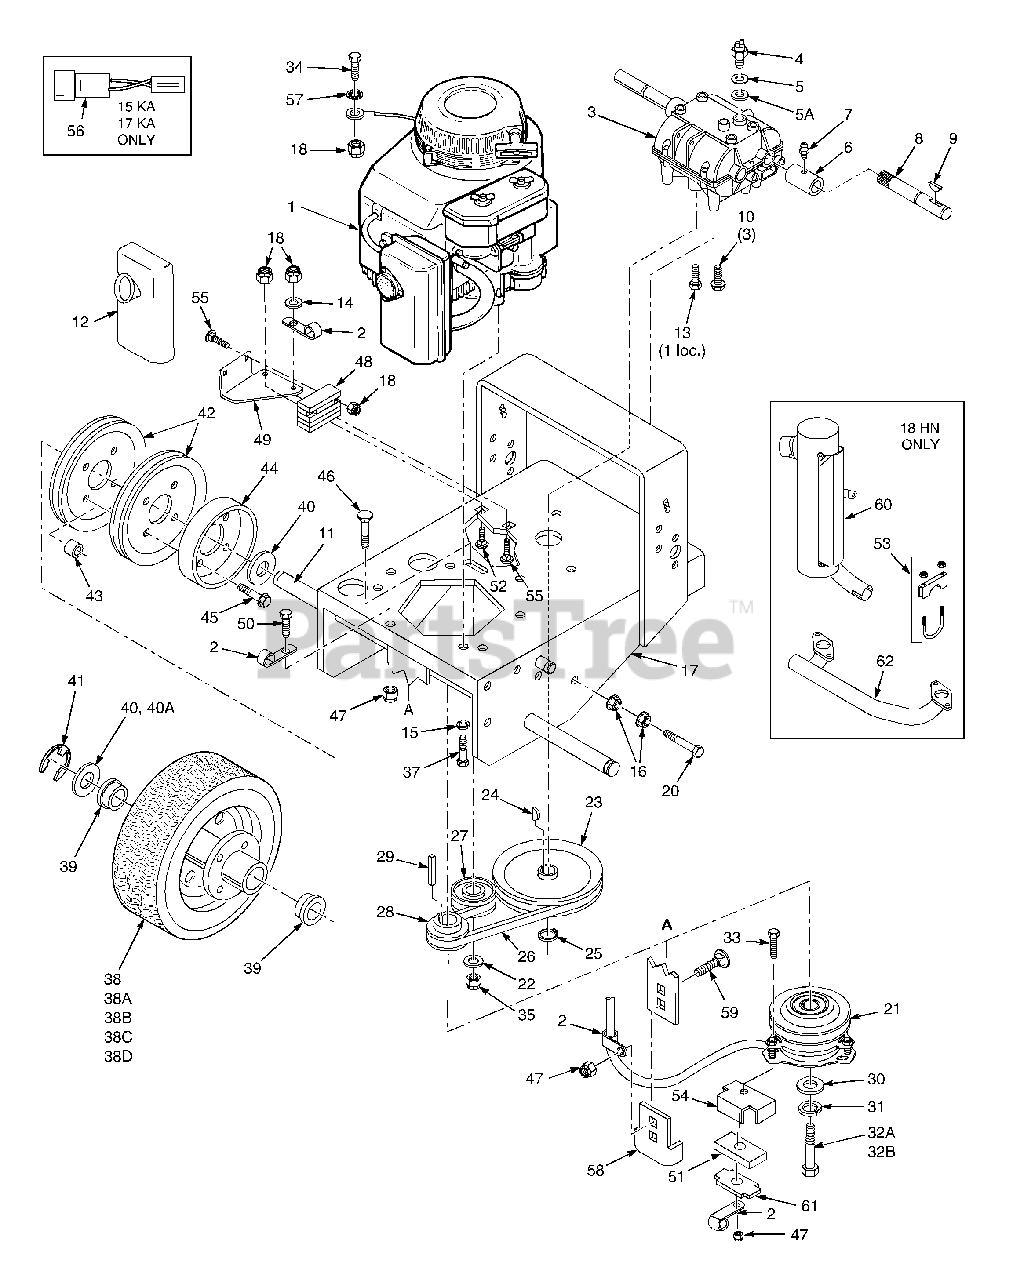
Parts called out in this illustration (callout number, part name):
1	Engine, 15HP Kawasaki (Spec FH451V-AS19)
1	Engine, 17HP Kawasaki (Spec FH500V-AS42)
2	Cable Clamp
3	Transmission, 5-speed (Peerless 700-070, 9 tooth spline)
4	Neutral Safety Switch
5	Fibre Washer, thin
5A	Fibre Washer, thick
6	Coupler, Jackshaft
7	Grease Fitting, straight 1/4-28
8	Jackshaft (fits SW32,36,48 & 52)
9	Key, Hi-Pro #9
10	Bolt, 5/16-18 X 3/4" Carriage
11	Wheel Axle (SW36,48 & 52)
12	Muffler (Purchase from Kawasaki)
13	Bolt, 5/16-18 X 3/4" Hex Head
14	Flat Washer 1/4" (.312 X .75 X .065)
15	Lock Wshr. 5/16"
16	Nut, 3/8-16 Serrated Flange
17	Engine Deck (fits SW32)
18	Nut, 1/4-20 Elastic Stop
19	Nut, 5/16-18 Serrated Flange
20	Bolt, 3/8-16 x 3-3/4" Hex Head
21	Electric Clutch (Ogura)
22	Washer, 3/8" (.391 x .938 x .105)
23	Pulley, Transmission Input
24	Key, Woodruff #9
25	Retaining Ring, 5/8" Ext, Basic
26	Belt, Transmission Drive
27	Idler Pulley, Transmission
28	Pulley, Traction Drive
29	Key, 1/4 x 1/4 x 3/4"
30	Flat Washer, 7/16" Special
31	Lock Washer, 7/16"
32A	Bolt, 7/16-20 x2-1/2" Hex Head
32B	Cpsrw, M10-1.5 x 55 Metric Hex Hd
33	Bolt, 5/16-18 x 1-3/4" Hex Head
35	Nut, 3/8-16 Elastic Stop
36	Flat Washer, 5/16"
37	Bolt, M8-1.25 x M25 Metric Hex Hd
38	Wheel Assembly (fits SW36,48,52)
38	Wheel Assembly
38A	Tire, 13 x 6.50-6, 2-ply (fits SW36,48,52)
38B	Rim & Bearing Assembly (fits SW36,48 & 52)
38C	Tire, 13 x 5.00-6 2-ply (SW32 only)
38D	Rim Assembly (SW32 only)
39	Wheel Bearing (OD 2.000 - 2.005)
40	Washer, 1-1/16 x 1-3/4 x 12 ga
40A	Washer, 1-1/16 x 1-1/2 x 18 ga
41	Retaining Ring, 1" Ext.- "E"
42	Pulley, Wheel Drive
43	Spacer, Wheel Pulley
44	Brake Drum
45	Bolt, 5/16-18 x 1-1/2" Serrated flange
46	Bolt, 3/8-16 x 2" Carriage
47	Nut, 5/16-18 Elastic Stop
48	Rectifier (Purchase from Honda)
49	Mounting Bracket, Rectifier
50	Bolt, 5/16-18 x 1" Hex Head
51	Rubber Pad, Clutch Stop
52	Bolt, 1/4-20 x 3/4" Carriage
53	Clamp, Muffler
54	Backing Plate
55	Bolt, 1/4-20 x 1" Carriage
56	Wire Harness Adapter (15KA & 17KA)
57	Lock Washer Internal Tooth
58	Anti Rotation Bracket
59	Bolt, 5/16-18 x 1" Carriage
60	Muffler
61	Plate, Backing
62	Manifold, Exhaust
